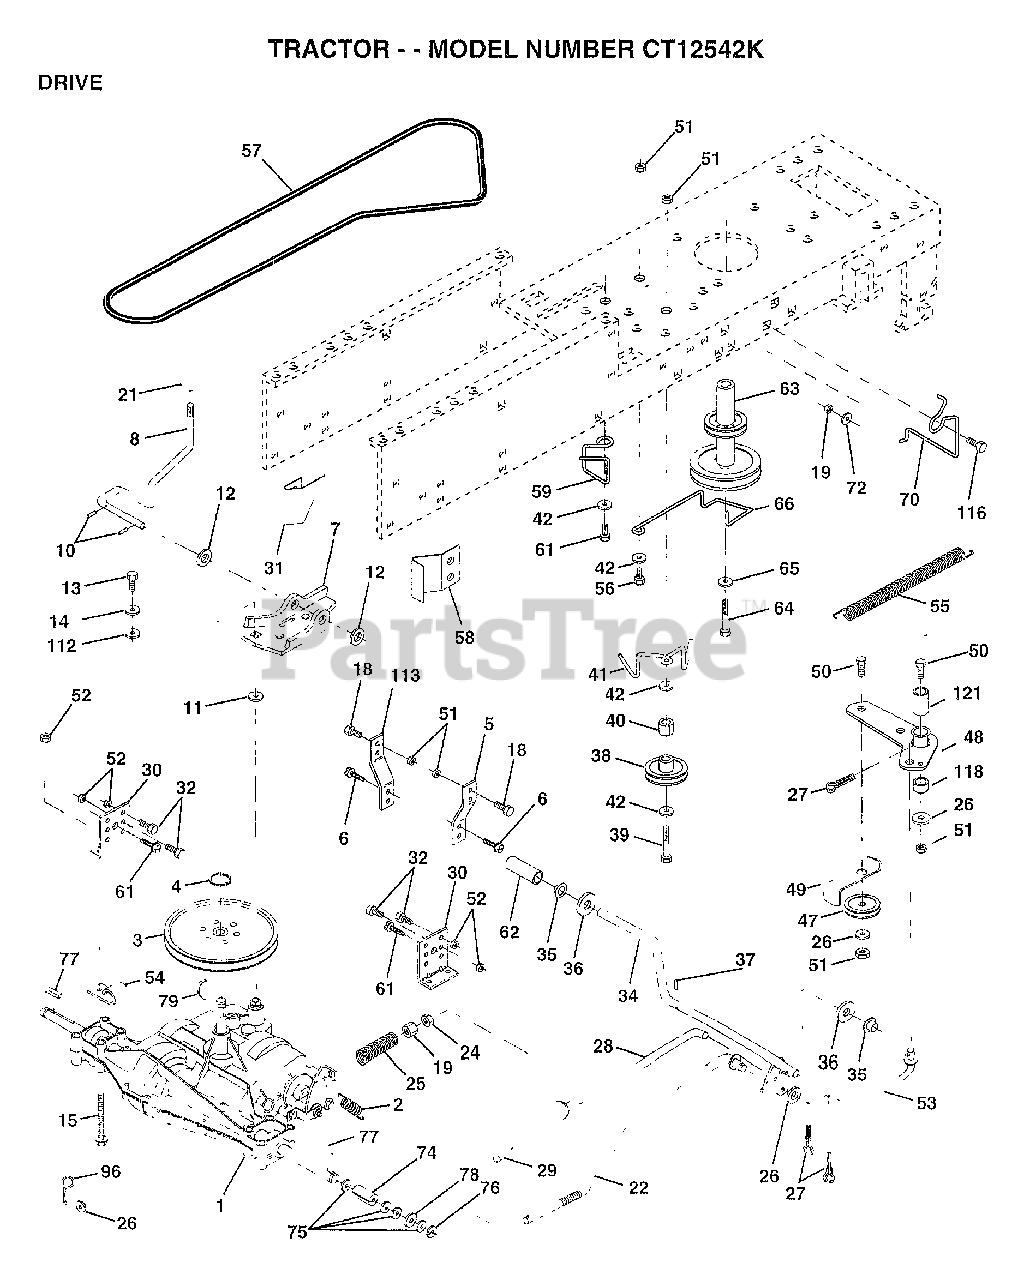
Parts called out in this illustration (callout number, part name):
2	SPRING.BRAKE.RETU
3	PULLEY TRANS
5	STRAP TORQUE
6	SCREW
8	SHIFT ROD
10	PIN COTTER 1/8
11	WASH-SHFT PLT LT
12	WASHER
13	BOLT.1/4-28.W/PAT
14	LOCKWASHER
15	BOLT.HX.FLG.5/16
18	BOLT
19	NUT
21	KNOB T (1/2-HOLE)
22	BRAKE ROD
24	NUT
25	SPRING ROD LT
26	WASHER
27	COTTER PIN
28	ROD.BRAKE.PARK.LT
29	PLUNGER CAP T
30	TRANSAXLE MTG BKT
31	"KEEPER,BELT LH T"
32	BOLT
34	SHAFT ASM-PEDAL F
35	NYLON BEARING
36	WASHER LT
38	PULLEY.IDLER.FLAT
39	BOLT
40	SPACER T
42	WASHER
48	BELLCRANK ASM
49	RETAIN BELT
53	"LINK, CLUTCH T"
54	CLIP T
55	"SPRING, RETURN LT"
58	"KEEPER,BELT RH T"
59	KEEPER BELT CNTSP
61	SCREW
62	PEDAL COVER T
63	PULLEY.ENGINE
64	BOLT
65	LOCKWASHER
66	KEEPER-BELT
70	KEEPER BELT ENG
72	WASHER
74	SPACER AXLE
75	WASHER
76	E-RING LT
77	SQUARE KEY
78	WASHER
96	RETAINER M
112	WASHER LT
113	"STRAP,TORQUE"
116	BOLT RDHD 3/8-16
118	SPACER-BELLCRANK
121	NYLINER-CLUTCHING
